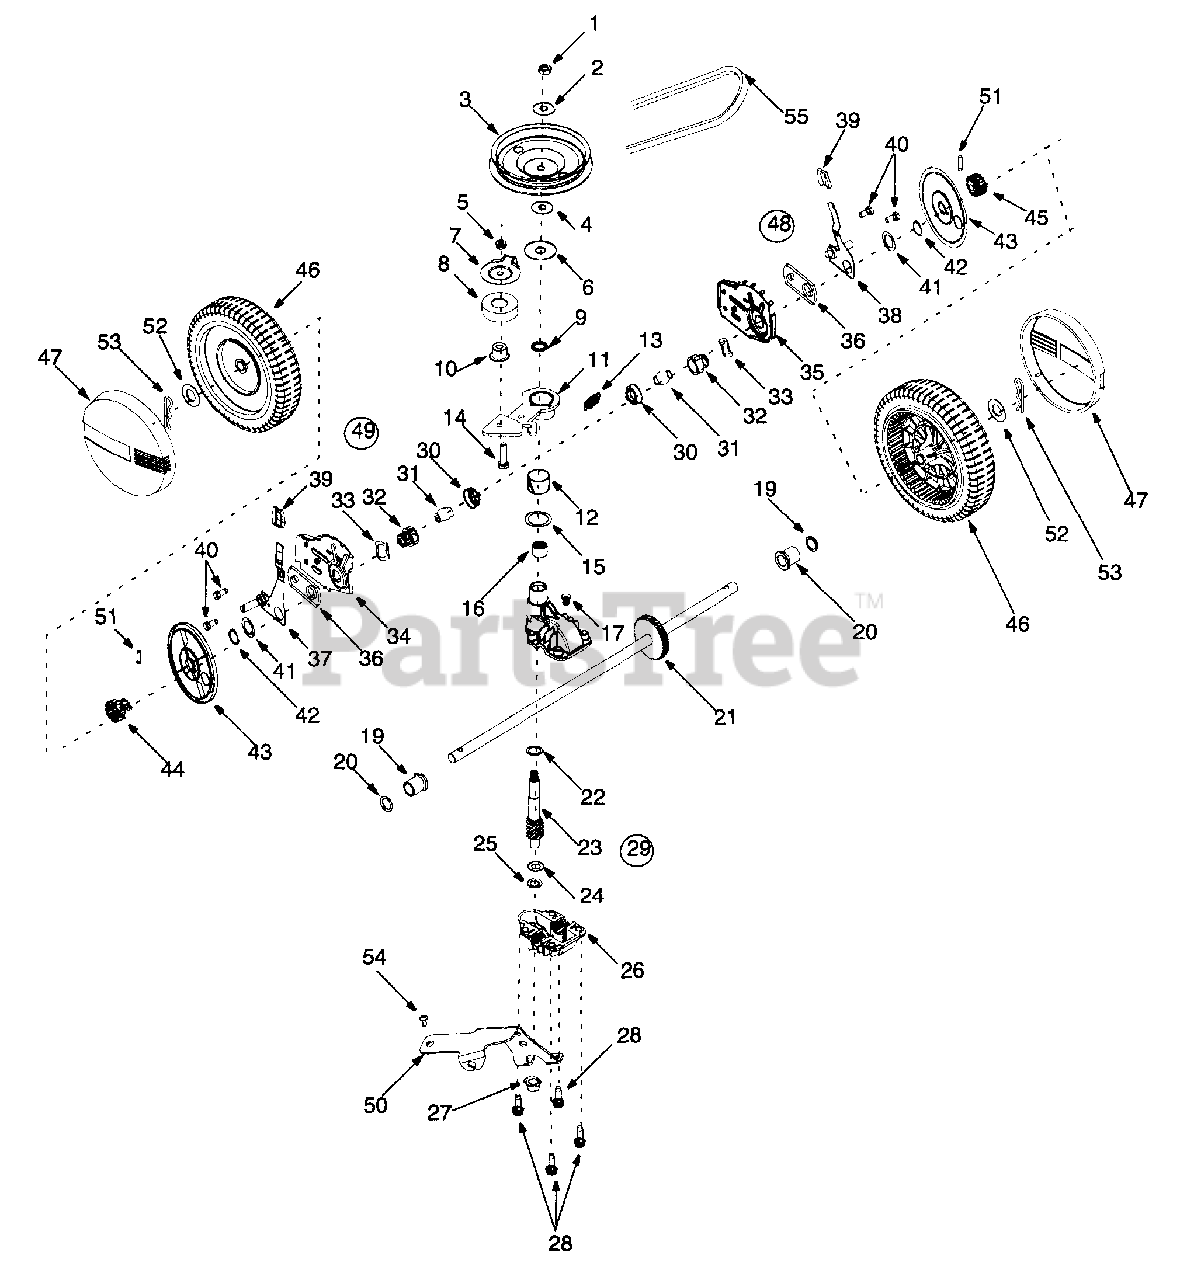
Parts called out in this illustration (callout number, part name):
1	Hex Jam Nut 5/16-24
2	Bell Washer .325 x .930 x .045
3	Pulley
4	Bell Washer .325 x .930 x.045
5	Lock Nut 1/4-28
6	Flat Washer .442 x 1.38 x .060
7	Belt Keeper
8	Ball Bearing
9	Oil Seal
10	Flange Spacer
11	Idler Bracket Assembly
12	Bearing Sleeve
13	Flat Washer .504 x .700 x .030
14	Hex Cap Screw 1/4-28 x 1.00 Gr. 5
15	Flat Washer .665 x 1.145 x .030
16	Needle Bearing .438 x .625 x .500 Lg.
17	Plug 1/4 x .437
19	Oil Seal .500 x .687 x .094
20	Flange Bearing
21	Output Shaft
22	Flat Washer .504 x .700 x .030
23	Pinion Shaft 10T
24	Thrust Washer .375 x .70 x .030
25	Thrust Washer .388 x .625 x .062
26	Lower Housing
27	Flange Bearing .378 x .531 x .370
28	Hex Scr. w/Washer 1/4-20 x .750
29	Transmission Assembly
30	Bearing Retainer
31	Bearing Sleeve .50 I.D.
32	Bearing Support
33	Wave Washer 1.5 x 1.0 x .029
37	Front Lever RH
38	Front Lever LH
39	Knob
40	Hex Cap Screw 3/8-16 x .75
41	Washer DD 1.5" O.D.
42	Snap Ring 1.0 dia.
43	Wheel Dust Cap
44	Gear 14T RH FWD
45	Gear 14T LH FWD
46	Wheel: 8 x 2 Yellow, Link Trd.
47	Hubcap: Yellow
48	Height Adj, Complete RH
49	Height Adj, Complete LH
50	Cable Idler Bracket
51	Dowel Pin
52	Flat Washer 1/2 x 1. 00 x .063
53	Cotter Pin .08 x 1.42
54	Screw
55	Belt
